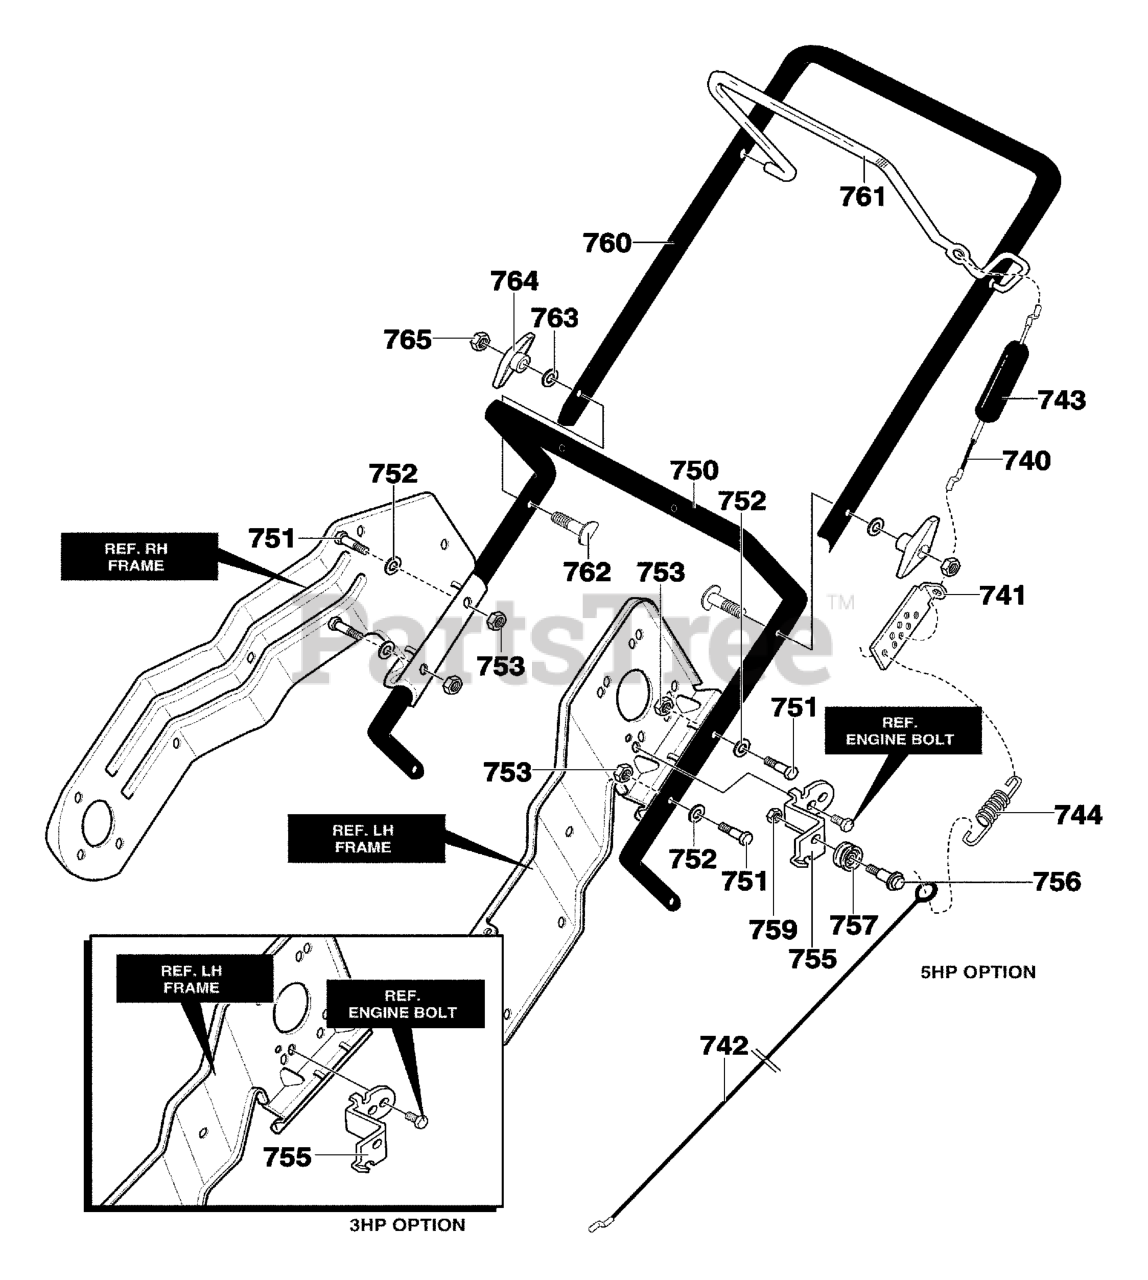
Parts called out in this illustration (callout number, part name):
740	CABLE, UPPER
741	BRKT, CABLE ADJ
742	CABLE LOWER CONTROL
743	BOOT, CLUTCH SPRING
750	HANDLE LOWER
751	SCREW, 1/4-20X1.25
752	WASHER, FLAT .281X.63X.065
753	NUT, 1/4-20
755	BRACKET, CABLE
756	BOLT, .375X.375 1/4-20
757	PULLEY, .906X.305
759	NUT, 1/4-20
760	HANDLE, UPPER
761	BAIL, CONTROL
762	BOLT, 5/16-18X2.00
763	WASHER, FORM
764	KNOB,T
765	NUT, 5/16-18
